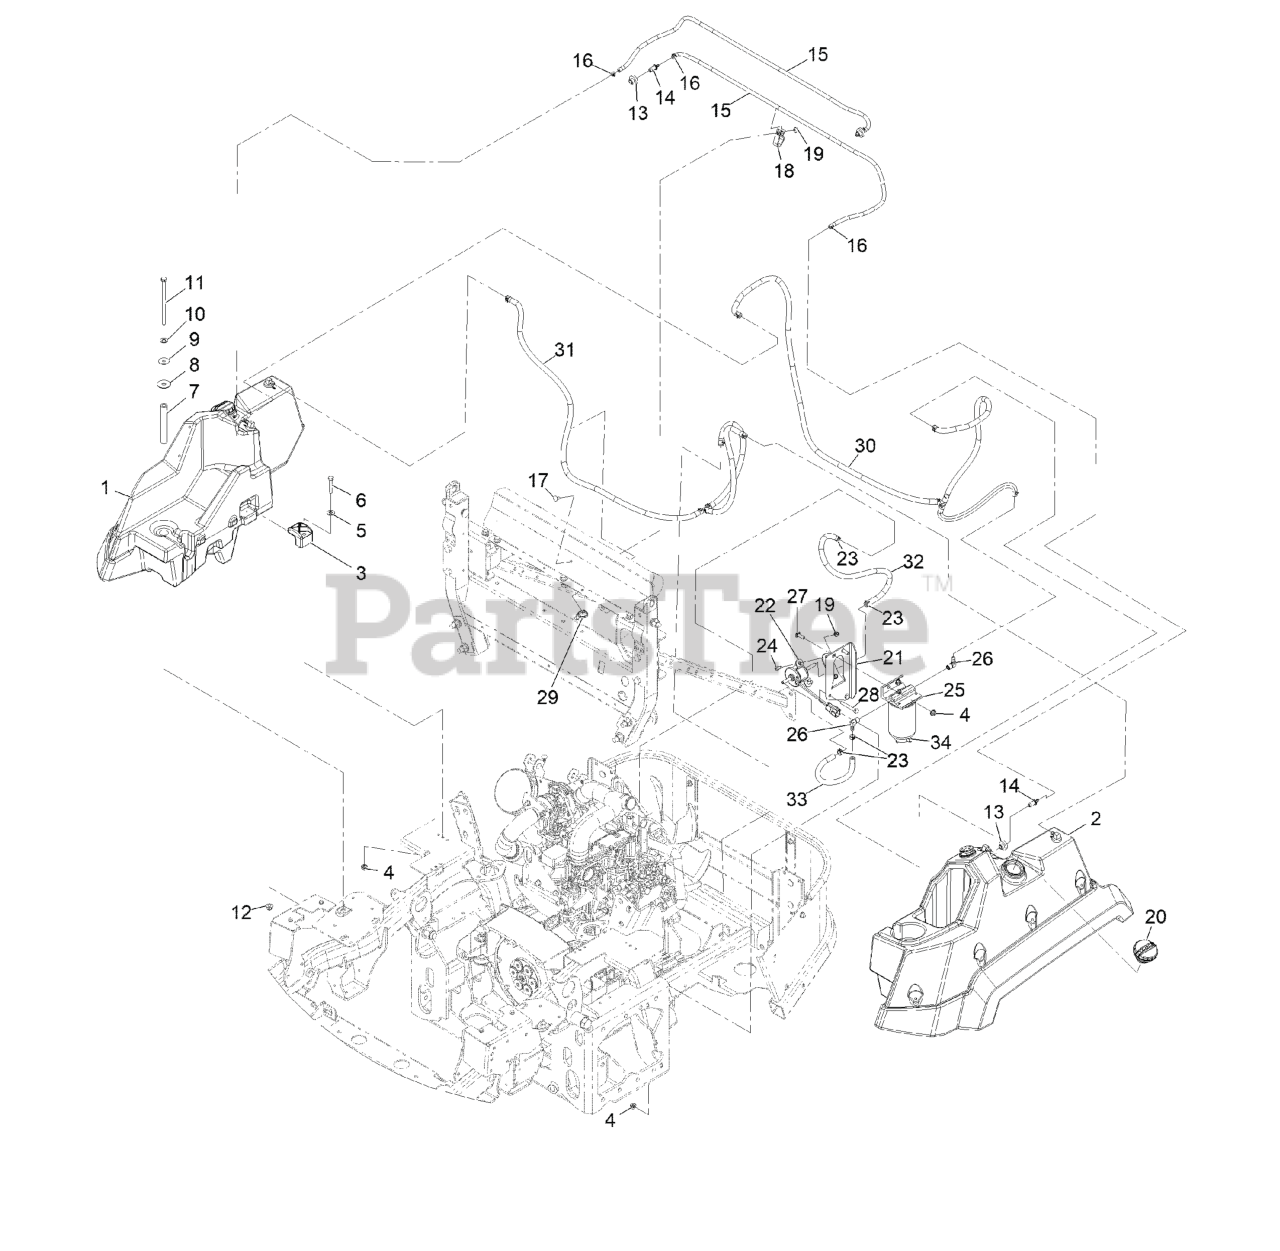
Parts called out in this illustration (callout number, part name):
1	RH FUEL TANK ASM
2	LH FUEL TANK ASM
4	NUT-HF, NI
5	WASHER-FLAT
6	SCREW-HH
7	TUBE-SPACER
8	WASHER-RUBBER
9	WASHER-PLAIN
10	WASHER-FLAT
11	SCREW-HH
12	NUT-HF, NI
13	BUSHING
14	FITTING-ORIFICE, STRAIGHT
15	HOSE-VENT, TANK
16	CLAMP-HOSE
17	SCREW-CARR
18	CLAMP-HOSE
20	CAP-FUEL, DIESEL
21	BRACKET-FILTER AND PUMP,
22	PUMP-FUEL, ELECTRIC
23	CLAMP-HOSE
24	SCREW-HWH
25	ASM,FUEL FILTER W/HEAD
26	FITTING-HYD, 90
27	SCREW-CARR
28	SCREW-HH
29	CLIP-TIE
30	LINE-FUEL, SUCTION
31	LINE-FUEL, RETURN
32	HOSE-FUEL
33	HOSE-FUEL
34	FILTER-FUEL
